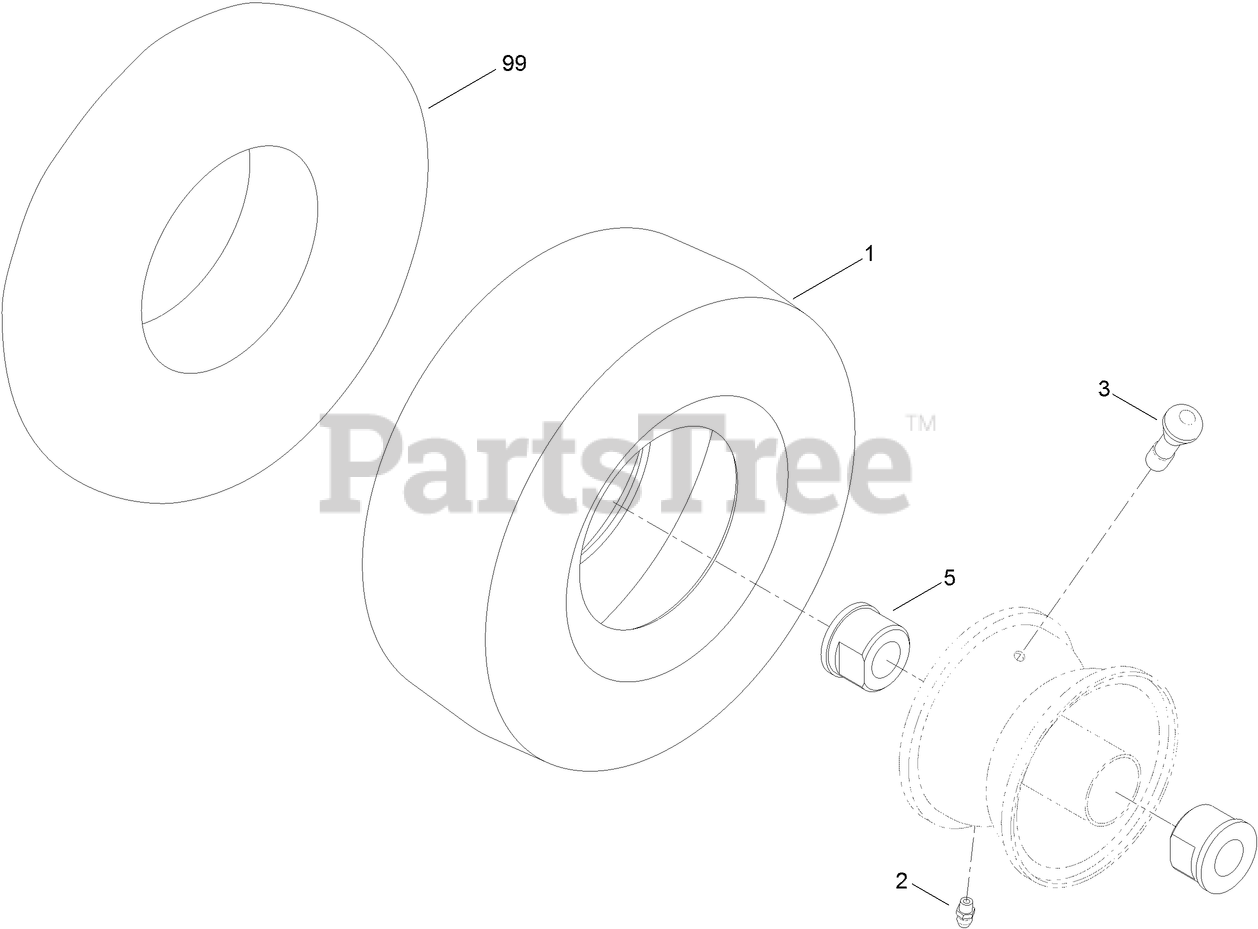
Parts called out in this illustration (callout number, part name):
1	TIRE-SMOOTH
2	FITTING-GREASE
5	BUSHING-FLANGE
99	TUBE-INNER (W/VALVE)
